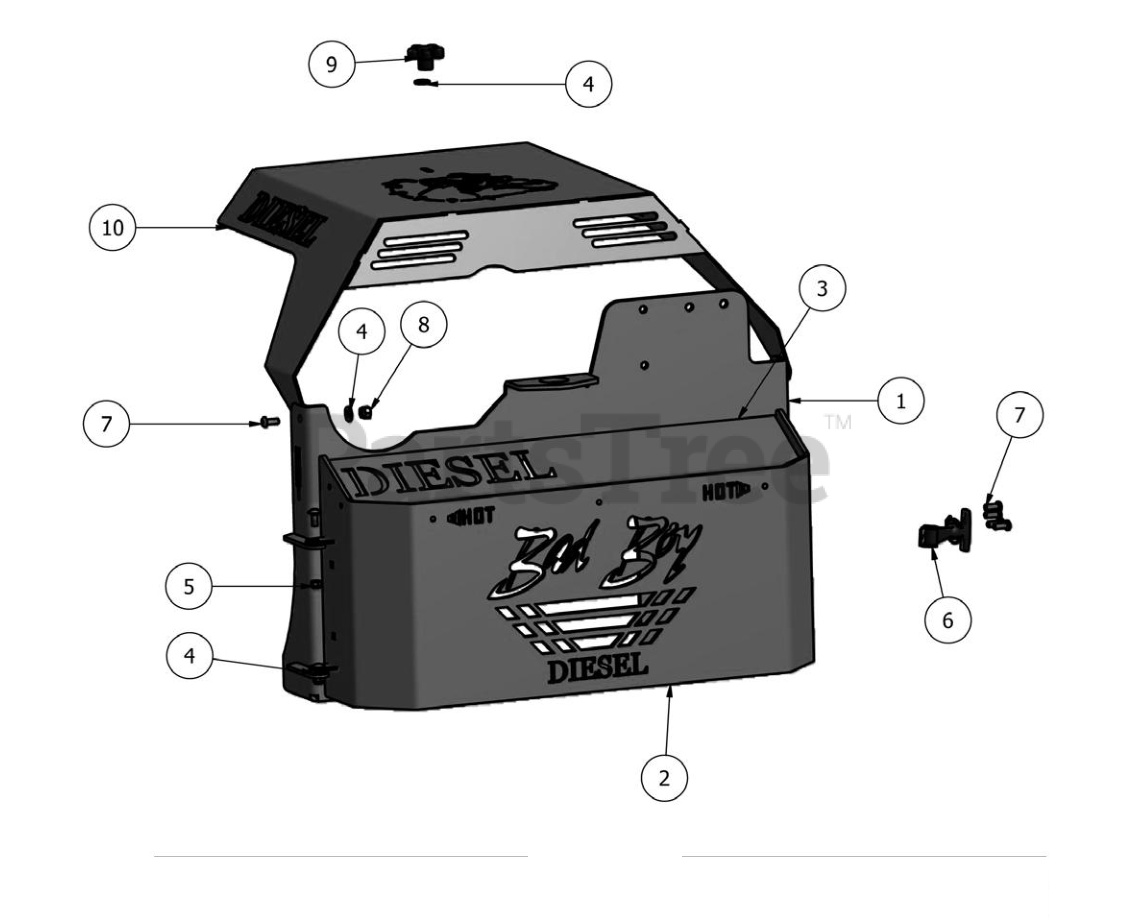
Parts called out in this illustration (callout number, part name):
1	Pump Plate Diesel
2	Back Pump Cover
3	Top Back Cover
4	.360 ID Plastic Washer
5	5/16" Nylock Nut
6	Metal Pump Cover Latch
7	5/16" x 3/4" Button Head Bolt
8	3/8 Nylock Nut
9	5/16" Knob
10	35 HP Hood
